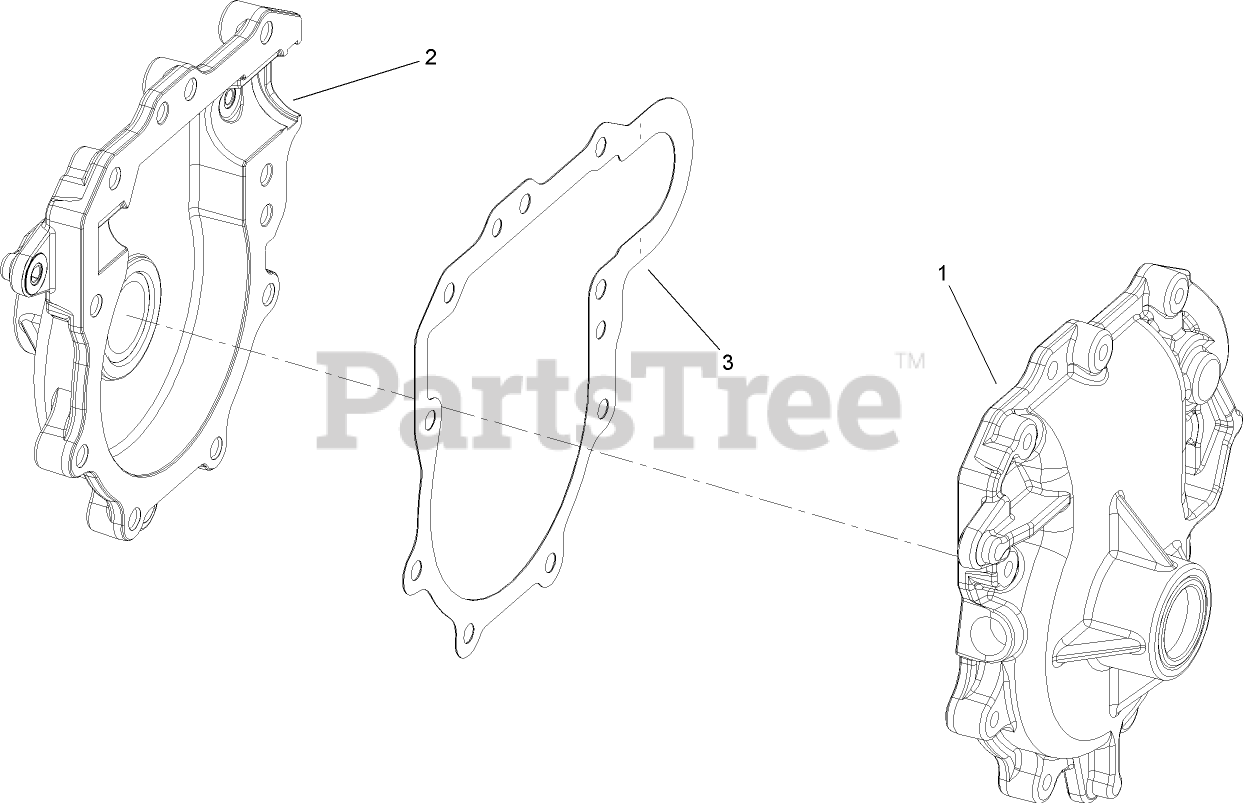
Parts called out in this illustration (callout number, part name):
1	LH AUGER GEARCASE ASM
2	RH AUGER GEARCASE ASM
3	GASKET-GEARCASE, AUGER
